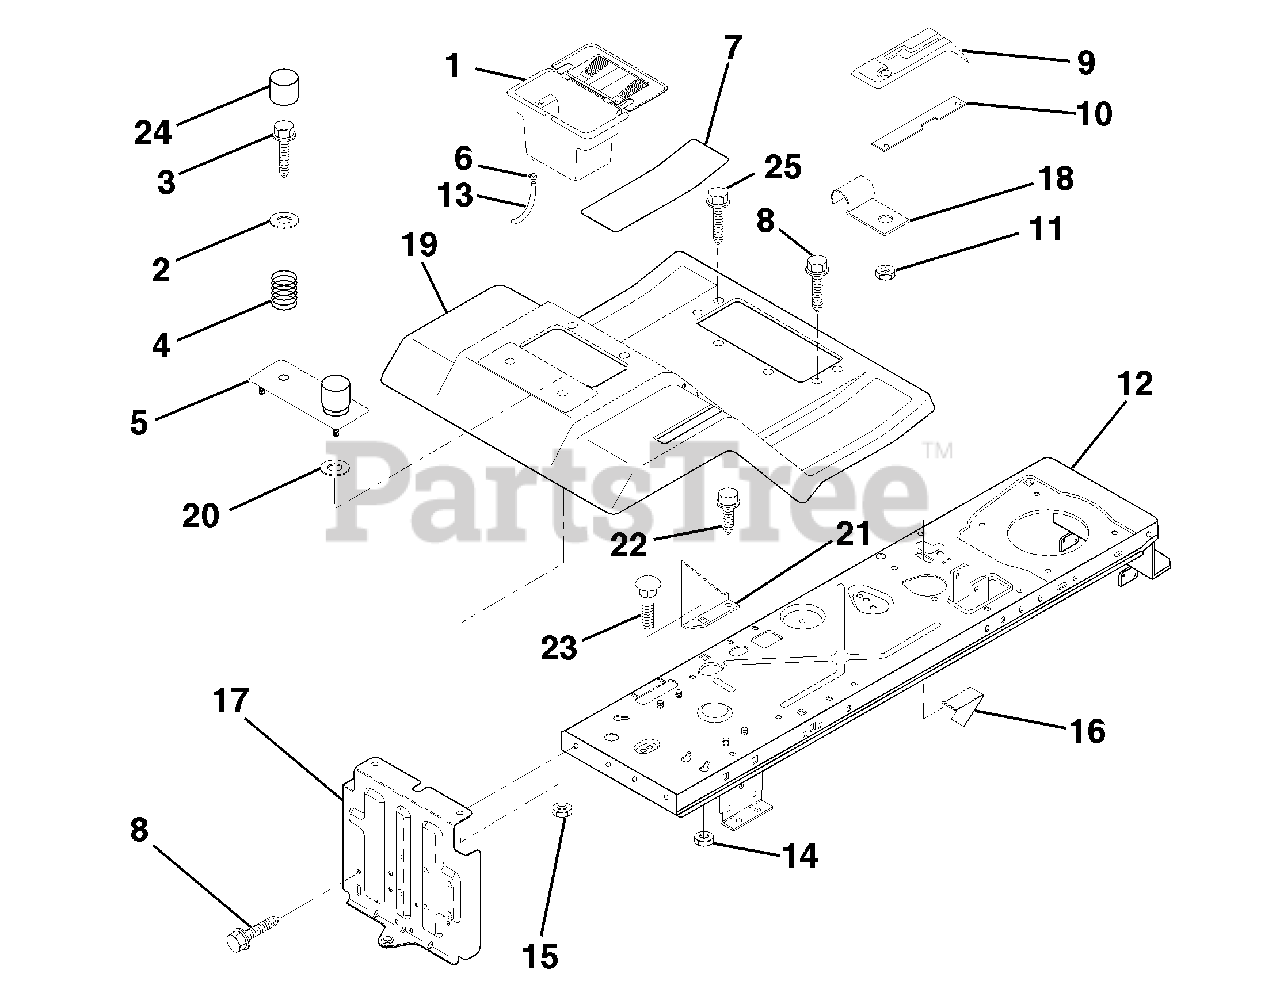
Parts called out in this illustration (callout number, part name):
1	Case Asm. Battery
2	Washer 13/32 x 1-1/4 x 12 Ga.
3	Screw Thdrol. 3/8-16 x 3/4
4	Spring seat
5	Plate Asm. Pnt Battery Fender
6	Clamp Hose Olive
7	Pad Footrest Rubber Deluxe
8	Screw Thdrol. 5/16-18 x 3/4
9	Console Shf. 6sp W/Ign.
10	Plate Lock Shift
11	Nut Self Thd. Wsh-Hd 1/4
12	Chassis Asm. Weldment
13	Tube Plastic
14	Nut Crownlock 5/16-18
15	Nut Keps Blk Hex 1/4-20 UNC
16	Switch Activator
17	Drawbar Asm.
18	Clip Insulated
19	Fend/Foot Asm. Pnt Shf. Fnd.
20	Washer 9/32 x 7/8 x 13 Ga.
21	Bracket Stop Depth
22	Screw Thdrol 5/16-18 x 1/2
23	Bolt Rdhdsqnk. 5/16-18 x 3/4
24	Cap Spring Seat
25	Scr-Hex Wsh Rol 5/16-18 x 1
